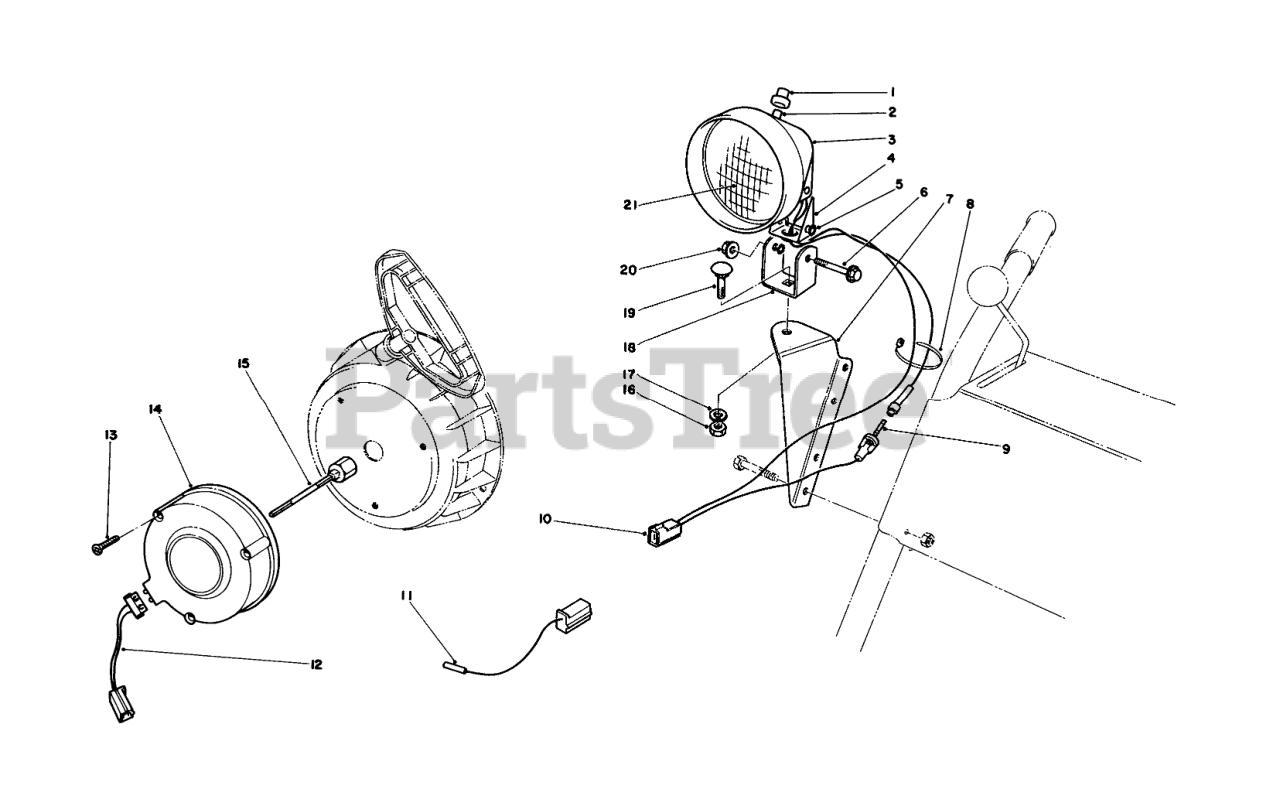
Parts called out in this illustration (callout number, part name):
1	BOOT-SWITCH
2	SWITCH ASM
3	Bucket-Headlamp
4	TO BE DISCONTINED-NOT NEEDED ON PRODUCT
5	WASHER-LOCK
6	SCREW-HH
7	LAMP MOUNT B
8	TIE-CABLE
9	Fuse-7 1/2 Amp
10	WIRE ASM
11	WIRE ASM
12	Connector-Wire
13	SELF TAP SCREW
14	Alternator
15	Shaft-Alternator, 3 Inch
16	NUT-HEX
17	WASHER-LOCK
18	BRACKET
19	BOLT-CARR
20	NUT-HF
21	SEALED BEAM
